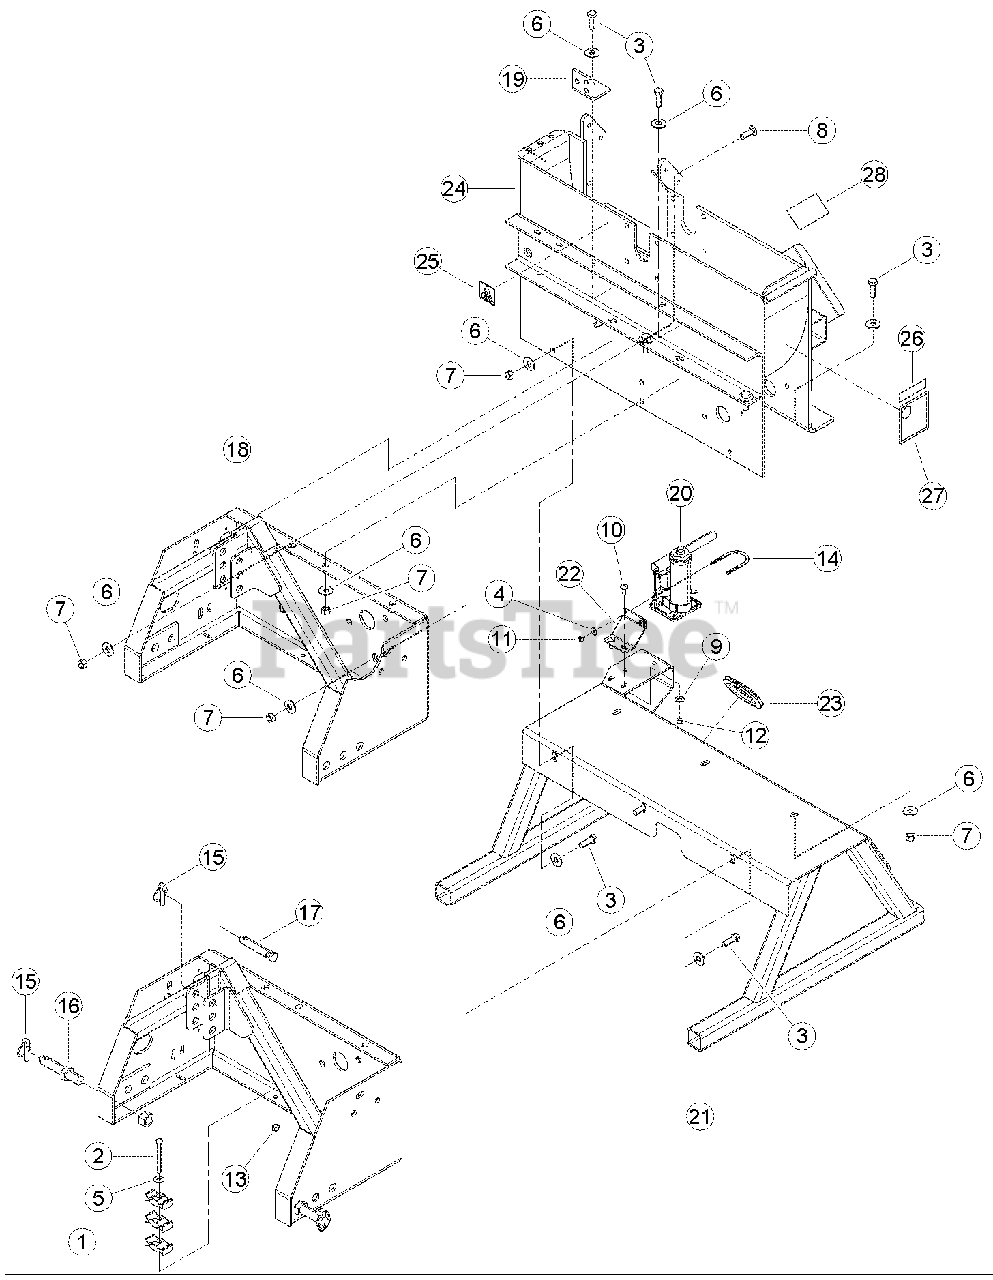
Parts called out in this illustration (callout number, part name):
1	CLAMP, PLASTIC HOSE
2	BOLT, 3/8 X 3-1/2 HEX HD GR5 ZP
3	BOLT, 1/2 X 1-1/2 HEX HD GR5 ZP
4	WASHER, 1/4 FLAT ZP
5	WASHER, 3/8 FLAT ZP
6	WASHER, 1/2 FLAT ZP
7	NUT, 1/2 CENTERLOCK GRB ZP
8	BOLT, 1/2 X 1-1/2 CRG GR5 ZP
9	WASHER, 5/16 FLAT ZP
10	BOLT, 5/16 X 7/8 CRG GR5 NC ZP
11	NUT, 1/4 NE NYLOCK ZP
12	NUT, 5/16 NE NYLOCK ZP
13	NUT, 3/8 NE NYLOCK ZP
14	U-BOLT, 1/4 X 1-1/2 PIPE
15	PIN, 7/16 X 1-3/4 LYNCH
16	PIN, LIFT ARM 7/8 X 5 LONG
17	PIN, TOP LINK 3/4 X 4-1/2 LONG
18	WELDMENT, HITCH SUPPORT
19	ANGLE, LOWER SHOCK
20	JACK, HYDRAULIC 2 TON
21	WELDMENT, PTO STAND
22	PLATE, JACK MOUNT
23	TRIM, SLOT EDGE COVER
24	ASSEMBLY, CH9540H BOTTOM HOUSING, SERVICE PART
25	DECAL, SHIELD DANGER ISO
26	DECAL,CH9540 INFORMATION
27	DECAL, 112 DB
28	DECAL, FEED SPEED
